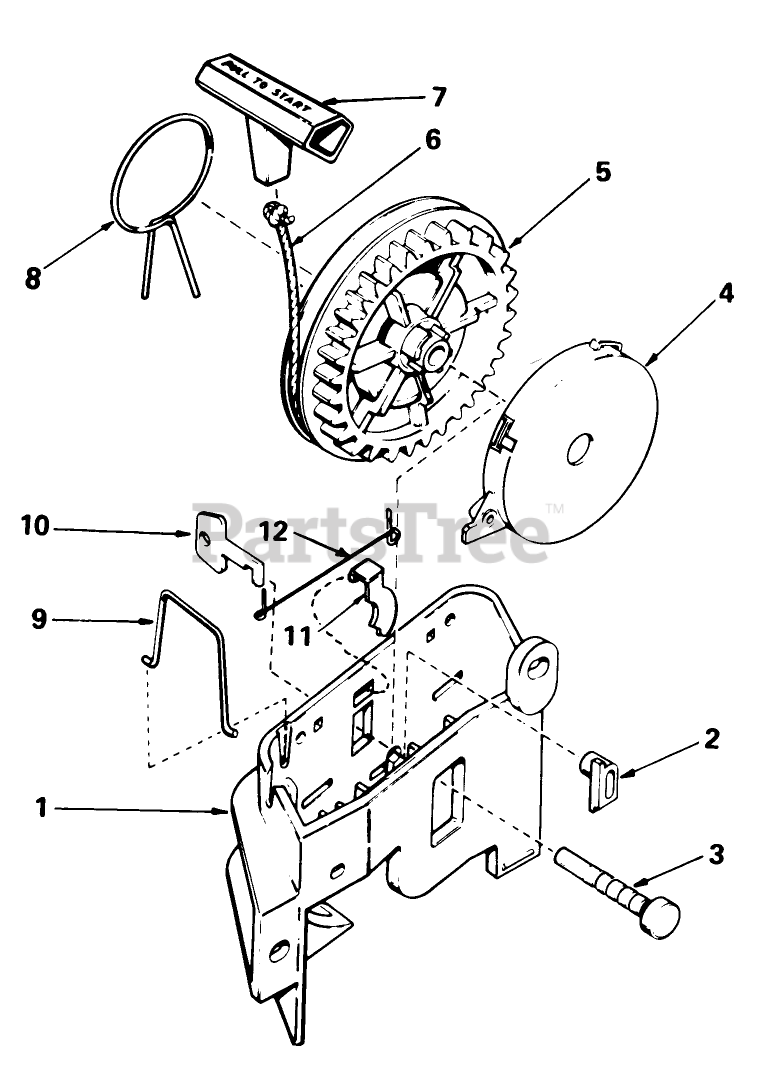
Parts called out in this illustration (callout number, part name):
1	Bracket Starter
2	Pawl, Locking Not used on all engine models)
3	Pin-Pulley
4	Spring Assy., Rewind (Incl. Ref. #3)
5	Pulley
6	Rope-Starter (98 cut to length)
7	Handle-Starter
8	Spring, Brake
9	Clip-Rope
10	Key (Not Used On All Engine Models
11	Pawl, Starter
12	Spring, Pawl
